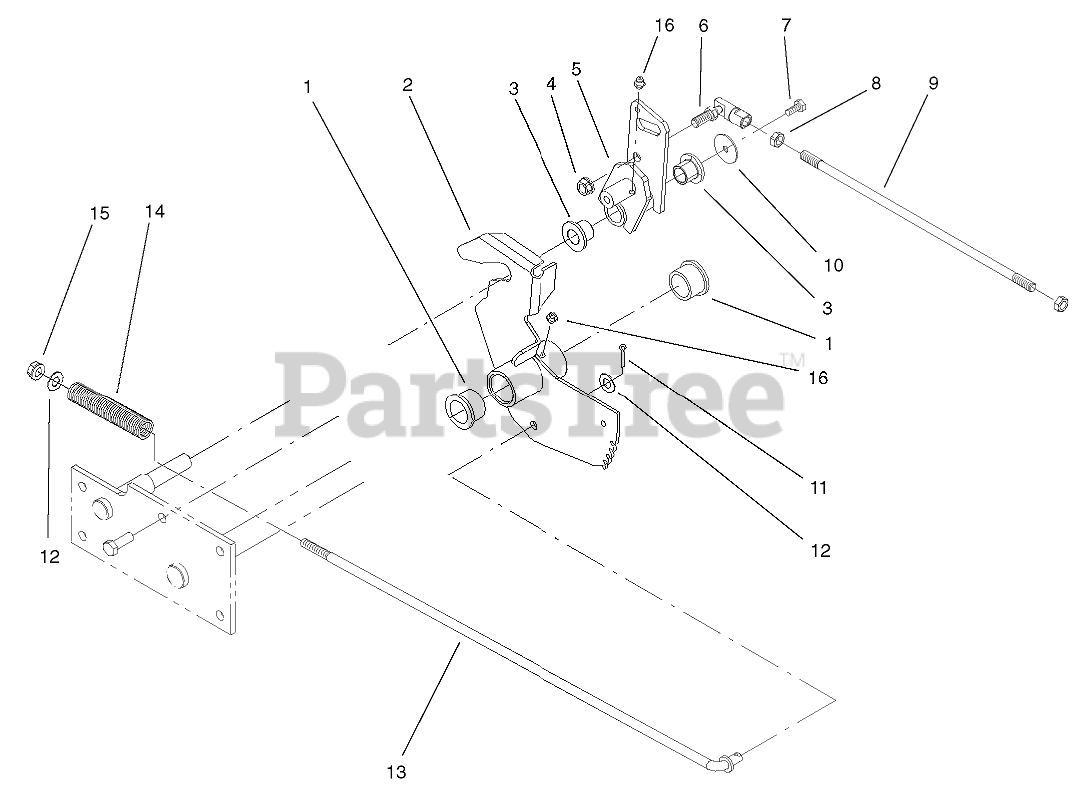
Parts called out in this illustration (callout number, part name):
1	BUSHING-FLANGED
2	PLATE-PIVOT, BRAKE
3	BUSHING
4	NUT-LOCK
5	PIVOT-HYDRO
6	END-TIE ROD, LH
7	SCREW-HH
8	NUT-JAM, LH
9	ROD-PIVOT TO PEDAL
10	WASHER-FLAT
11	PIN-COTTER
12	WASHER-FLAT
13	ROD-BRAKE
14	SPRING-COMPRESSION
15	NUT-LOCK, NI
16	FITTING-GREASE
